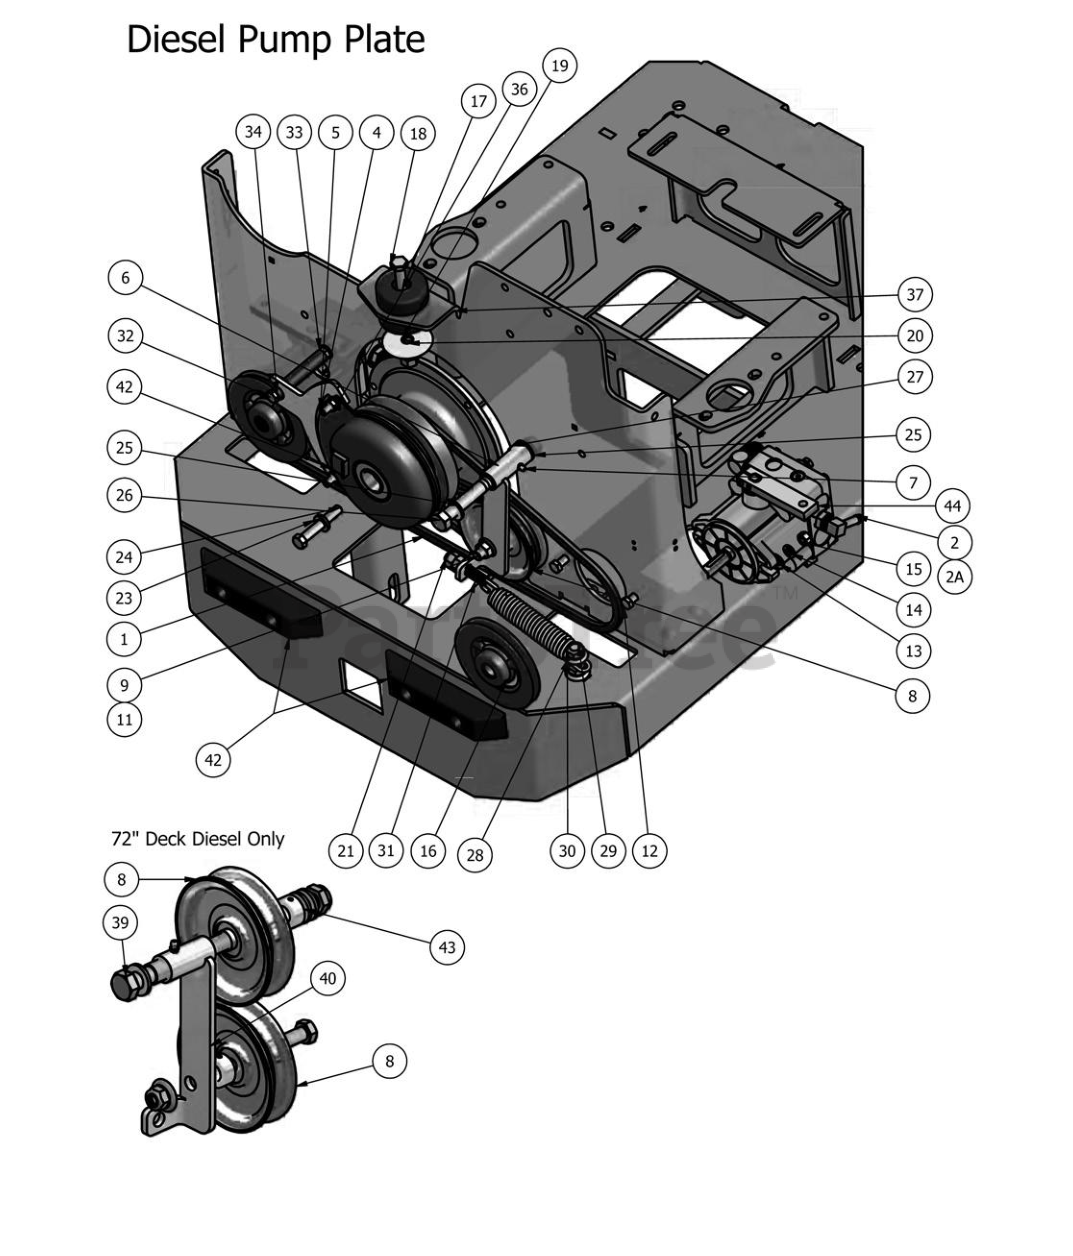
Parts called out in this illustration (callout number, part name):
1	Pump Belt, 72" Deck
1A	Pump Belt, 60" Deck
2	Hydraulic Pump Left
2A	Hydraulic Pump Right
3	Diesel Clutch
4	Diesel PTO Engager Holder
5	3/8" x 1 1/4" Carriage Bolt
6	Pump Idler Bracket (60 Only)
7	1/4" Drive-in Grease Fitting
8	4 3/4" Idler Pulley
9	1/2" x 2" Hex Bolt
10	5/8" x 1 1/8" Brass Bushing
11	1/2" Flange Nut
12	3/8" x 1 1/4" Hex Bolt
13	3/8" Flat Washer
14	3/8" Lock Washer
15	3/8" Hex Nut
16	5" Pump Pulley
17	Rubber Isolator
18	1/2" x 3" Bolt
19	1/2" Flat Washer
20	1/2" Lock Washer
21	1/2" Hex Nut
22	5/8" Nylock (1/2 Jam)
23	7/16" Lock Washer
24	7/16" x 2 3/4" Fine Thread Bolt
25	.635 ID Plastic Washer
26	5/8" x 4 1/2" Hex Bolt
27	1/2" Collar Spacer
28	6" Pump Idler Spring
29	1/2" x 2" Carriage Bolt
30	1/2" Nylon Flange Nut-Orange
31	1/2" x 2 1/2" All Thd Stud
32	3/8" x 4 1/2" Bolt
33	3/8" Flange Nut
34	Rubber Spacer
35	Stub Shaft
36	3/8" Nylock Flange Nut
37	Pump Plate Diesel
38	5" Idler Pulley
39	5/8" x 5 1/2" Hex Bolt
40	Diesel Pump Idler (72 Only)
41	Clutch Pigtail
42	8" Rubber Bumper
43	5/8" Set Collar
